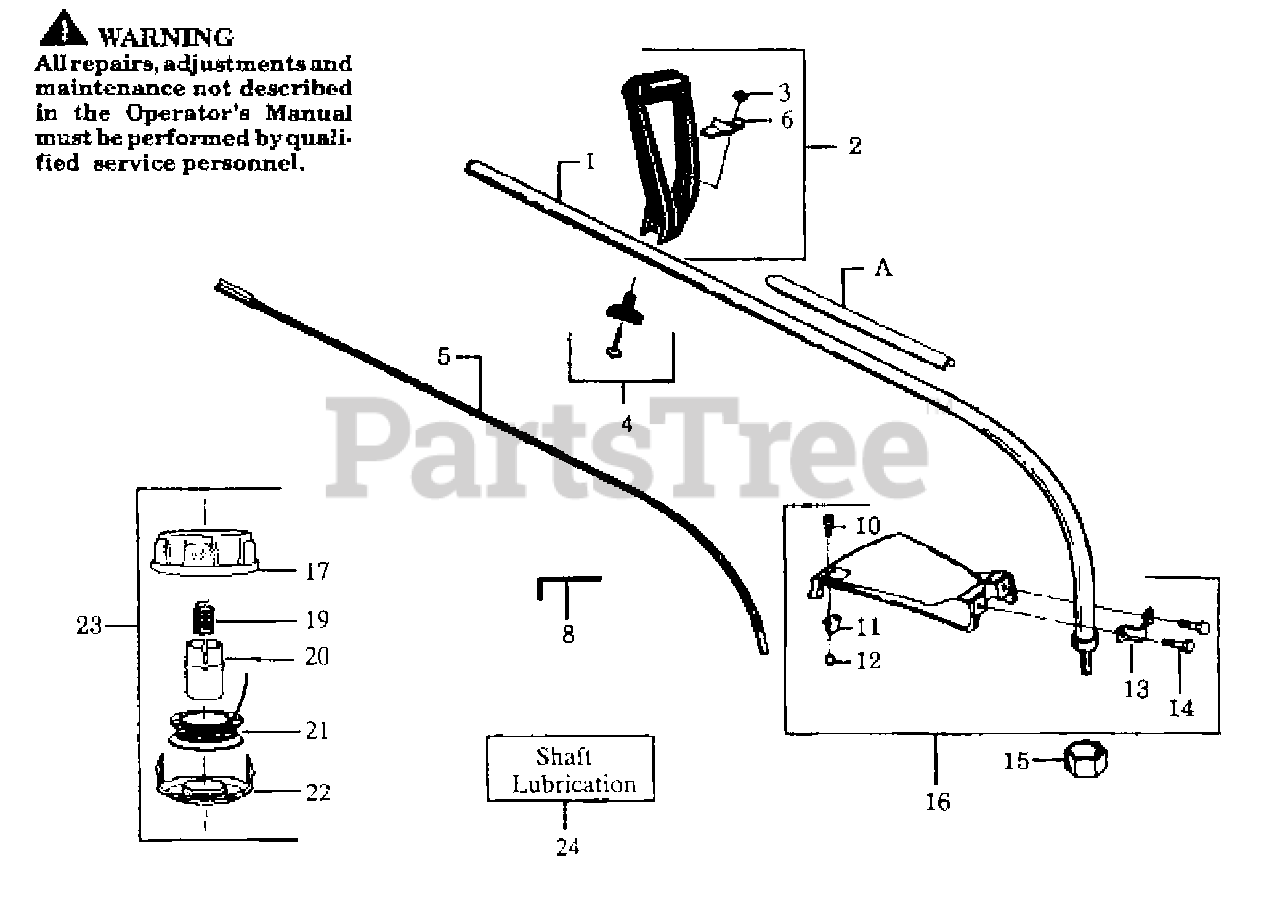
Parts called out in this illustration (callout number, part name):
1	Drive Shaft Housing
2	Assist Handle Kit
4	"T" Handle Ass'y.
5	Drive Shaft
8	Hex Wrench (5/32)
11	Line Limiter
12	Nut
13	Shield Bracket
14	Screw
15	Dust Cup
16	Shield Kit Ass'y.
17	Hub Ass'y.
20	Release Button
21	Spool w/Line
23	Cutting Head Ass'y.
24	Shaft Lubrication
A	Shaft Warning Decal
